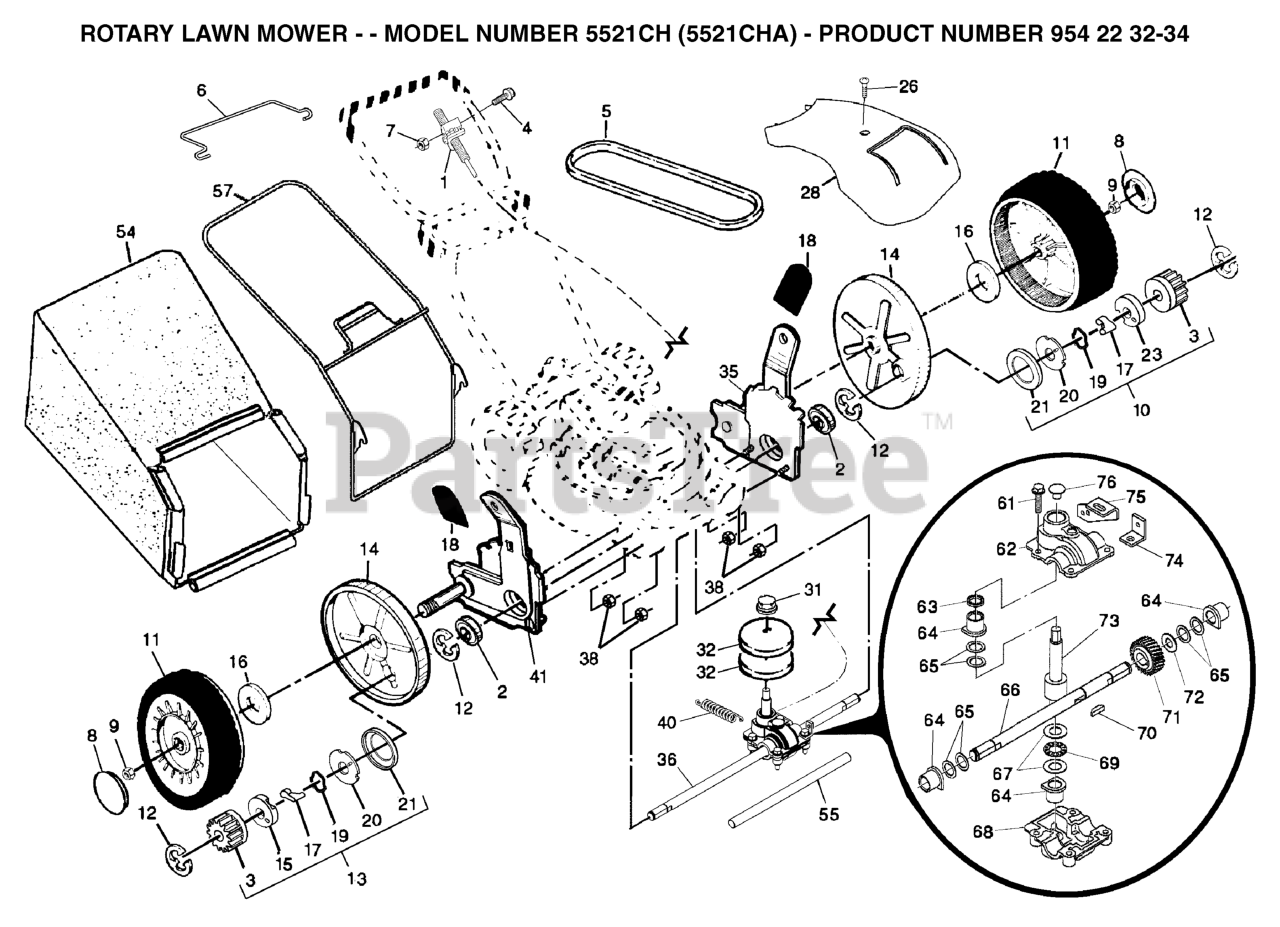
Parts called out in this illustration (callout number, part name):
1	VARI-SPEED DRIVE CONTROL ASSEM
2	BEARING, BALL
3	GEAR, PINION
6	BAR CONTROL DRIVE
7	LOCK NUT
8	HUBCAP
9	NUT
10	PINION/PAWL ASSY LH
11	WHEEL.8X2.PR.LP.RAD.BLK
12	E-RING 7/16 RE
13	PINION/PAWL ASSY RH
14	DUST COVER, WHEEL
15	RETAINER, DRIVE, RH
16	WASHER FLUT
17	PAWL.DRIVE.21.EZ-WALK
18	SELECTOR KNOB
19	SPRING, TORSION
20	DISC.DRIVE.21.EZ-WALK
21	SEAL, FRICTION
23	RETAINER.DRIVE.21.EZ-WALK.LT
26	SCREW, HEX HD TAPPING #10-24 1
28	COVER.DRIVE.21.FWGD.GRAY
31	FLANGED LOCKNUT 3/8-16 ZINC
32	DRIVE PULLEY
35	KIT.ADJUSTER.ASM.EZ.LH
36	GEAR CASE ASSEMBLY, COMPLETE
38	NUT
40	SPRING, RETURN
41	KIT.ADJUSTER.ASM.EZ(169770).RT
54	GRASS BAG
55	DRIVESHAFT COVER
57	FRAME.GBAG.21.HT/BAG
61	SCREW 14-20 X 5/8
62	GEAR CASE, UPPER, FWSS
65	THRUST WASHER
66	DRIVE SHAFT, 21" FWGD
67	WASHER, THRUST
68	GEAR CASE, LOWER, FWSS
69	BEARING, NEEDLE, THRUST
70	HI PRO KEY
71	GEAR, HELICAL (2 2MC)
73	SHAFT GEAR WORM
74	ARM.CLEVIS.ROD.SHIFT
75	BRACKET
76	PLUG.AUGER.GEAR.BOX.SNOW
